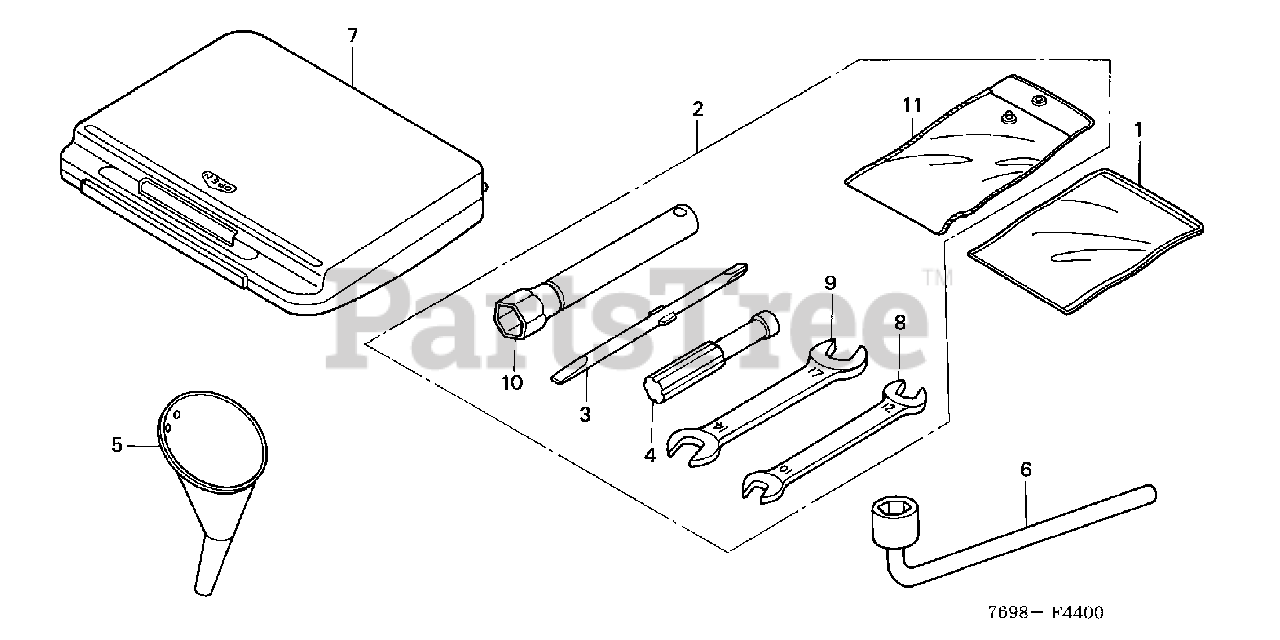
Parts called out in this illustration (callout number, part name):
1	BAG, OWNER'S MANUAL
3	SHAFT, SCREWDRIVER
5	FUNNEL, OIL
6	WRENCH, WHEEL NUT
8	WRENCH (10X12) (OPEN END)
9	WRENCH (14X17) (OPEN END)
10	WRENCH, BOX (P21)
